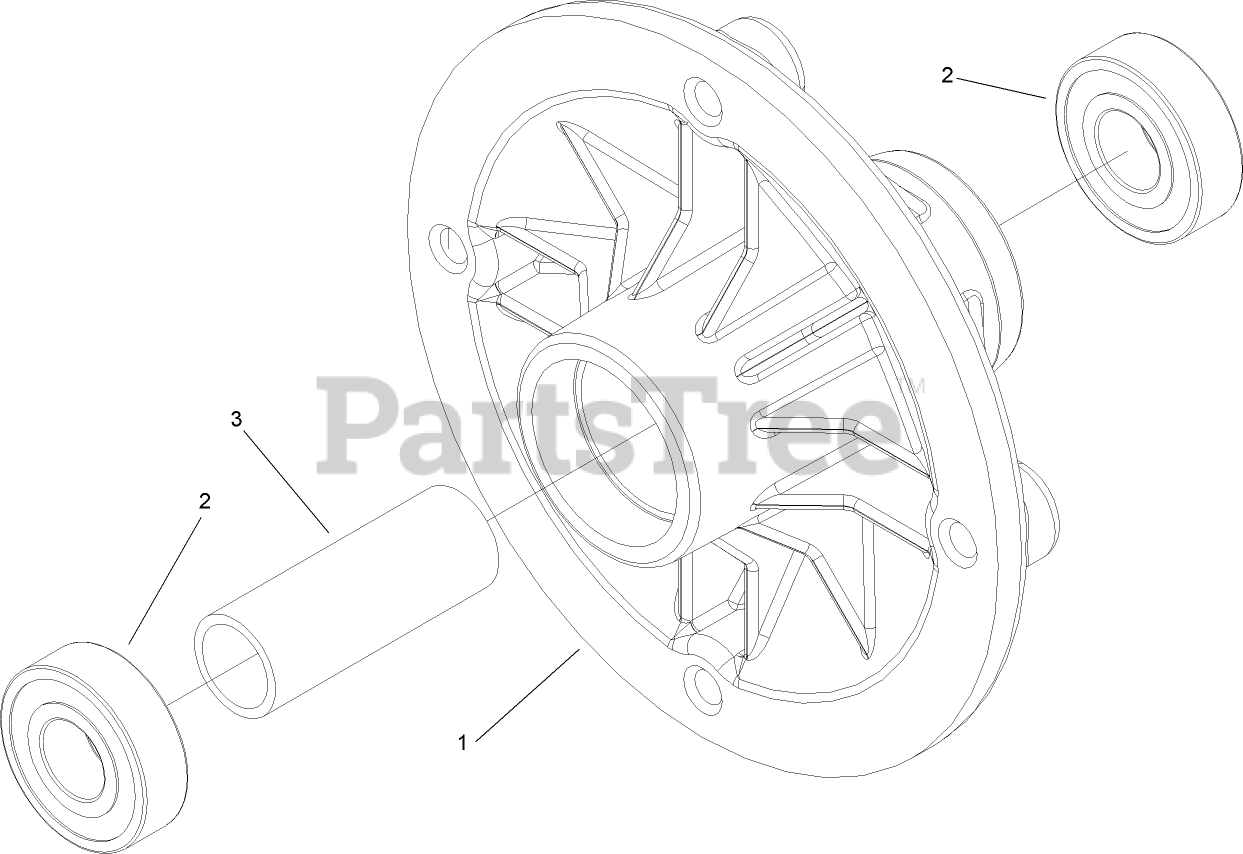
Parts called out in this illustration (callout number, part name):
1	HOUSING-SPINDLE
2	BEARING-BALL
3	SPACER
